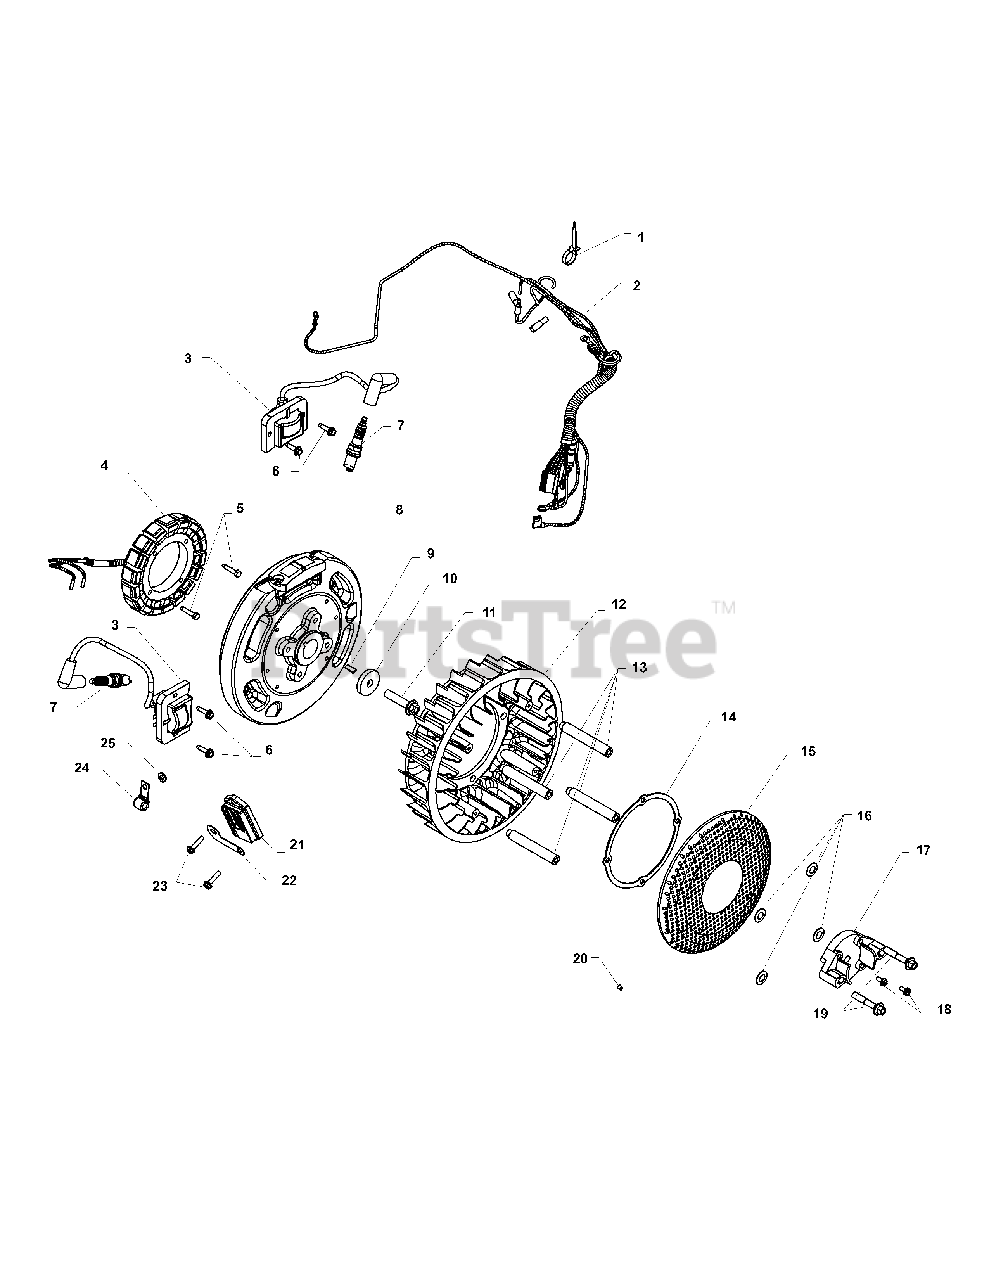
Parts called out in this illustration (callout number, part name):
2	Harness, Wiring Assembly
3	Kit, Module Ignition (CDI Fixed)
4	Kit, 15 Amp Stator
5	Screw, Thd Frm M5x0.8x25
6	Screw, Flg Thd Frm M5x0.8x20
7	Plug, Spark
9	Key, 3/16" X 5/8"
10	Washer, Flat 13/32"
11	Screw, Flg M10x1.5x45
12	Fan
14	Ring, Support
15	Screen, Grass
16	Washer, Spring 10 Mm
17	Adapter, Drive Shaft
18	Screw, Wsh HD Tap #8-18x1/2"
19	Screw, Flg M8x1.25x45
20	Screw, Skt Set #10-24x1/4"
21	Regulator, Rectifier
22	Bracket, Ground Strap
23	Screw, Hex Flange Hi-Lo
24	Clip, Cable
25	Washer, Flat 1/4"
